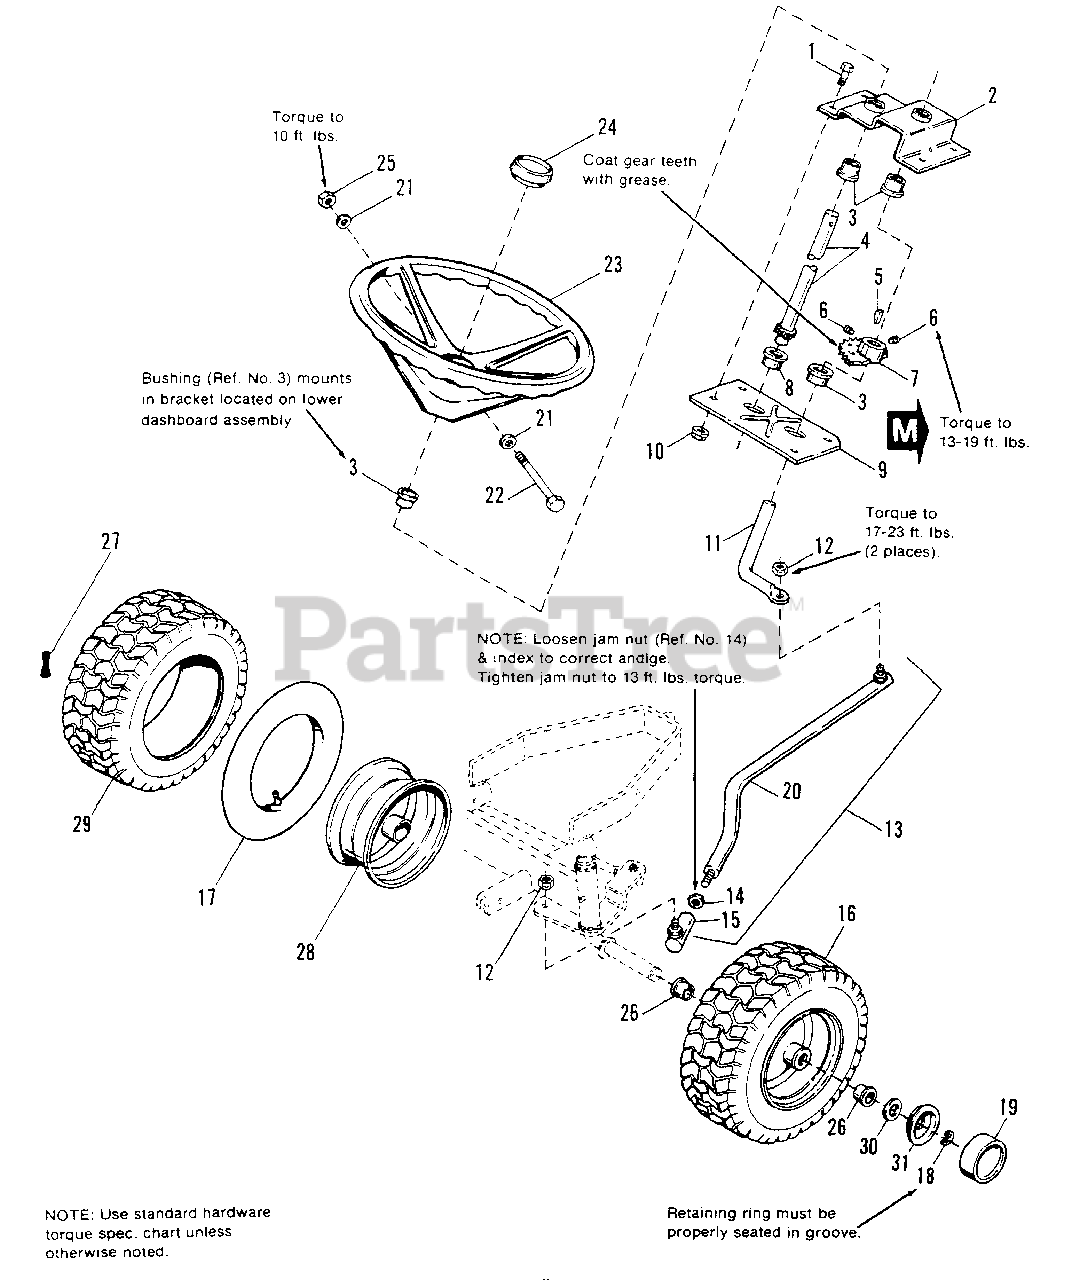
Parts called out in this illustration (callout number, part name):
1	CAPSCREW, Hex Hd., 5/16-18 x 3/4
2	PLATE, Steering
4	SHAFT ASSY., Steering
6	SETSCREW, 5/16-18 x 1/2
7	STEERING GEAR
9	BASE PLATE, Steering
10	NUT, Hex, Flange, 2 Way Lock, 5/16-18
11	ROD, Steering
12	NUT, Special
13	LINK ASSY., Drag (Incl. Ref. Nos. 14, 15 & 20)
14	NUT, Jam, 3/8-14
15	BALL JOINT ASSY.
16	WHEEL & TIE ASSY., 15 x 6-6 (Incl. Ref. Nos. 17, 26, 27, 28 & 29)
17	TUBE, 4.10 x 3.50-6 (Service Only)
18	KLIP RING, External, 3/4
21	WASHER, Plain, 5/16
22	BOLT, Hex, 5/16-18 x 3-1/2
23	WHEEL. Steering
24	CAP, Steering Wheel
25	NUT, Hex, Lock, 5/16-18
27	VALVE STEM
28	WHEEL
29	TIRE (Carlisle) 15 x 6.00-6
31	RETAINER, Hub Cap
